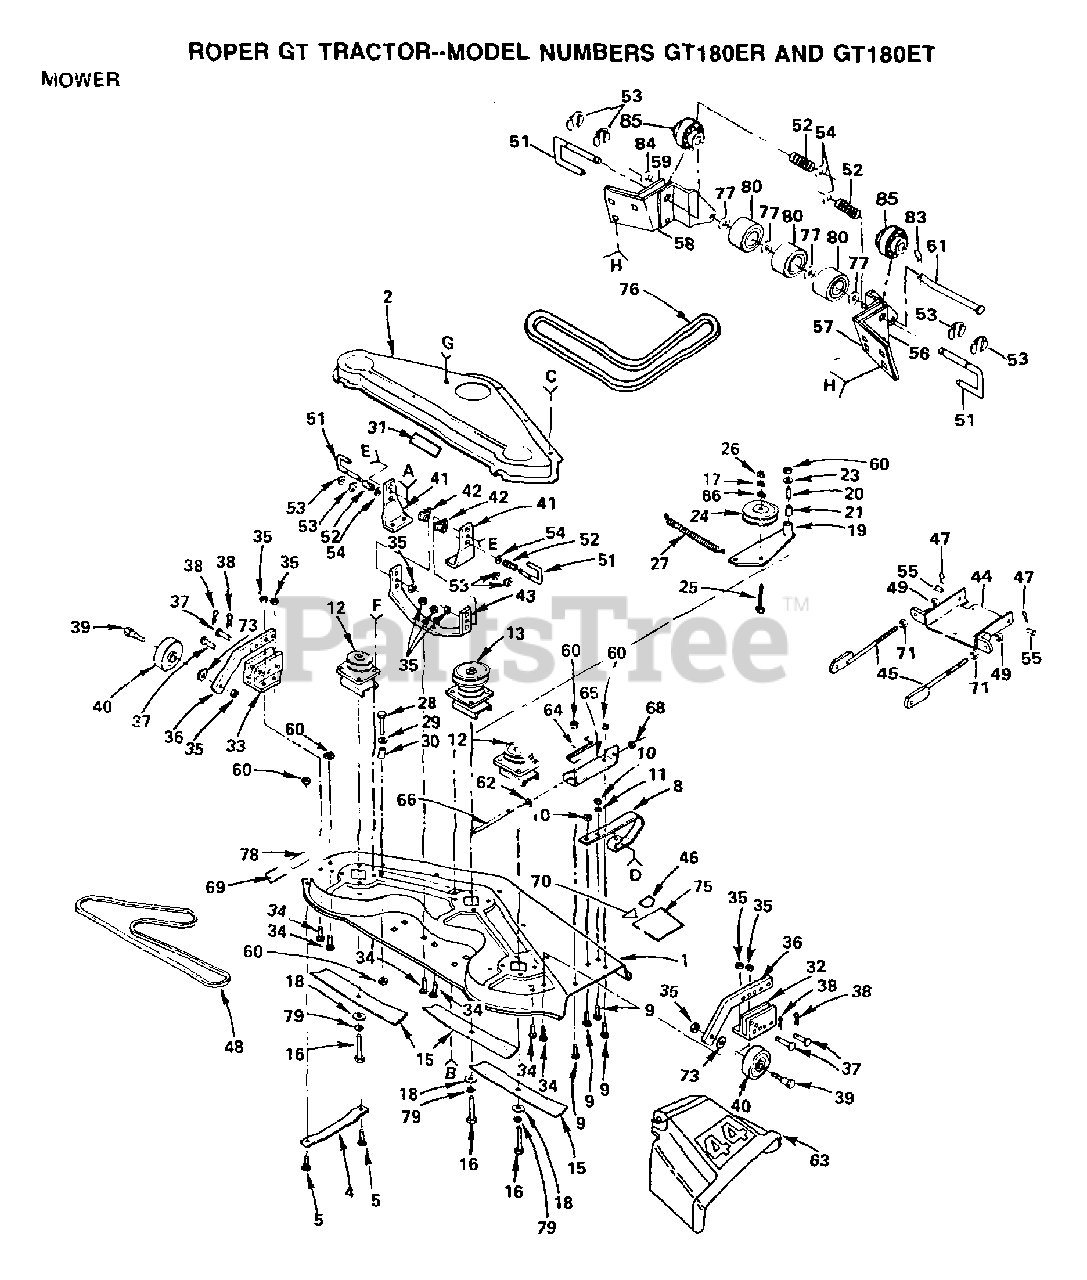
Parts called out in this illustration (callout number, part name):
2	DECK DRV COVE T
4	RUNNER-LH M
5	BOLT
9	BOLT
11	WASHER
16	BOLT.3/8-24X1-1/2
17	LOCKWASHER
18	WASHER
19	ARM ASSY GT
23	WASHER
24	IDLER-FLAT T
26	NUT.HEX.3/8-16UNC
27	SPRING T
28	BOLT
29	WASHER M
30	SPACER SPLIT LT
32	GUAGE WHL BRKT GT
33	GUAGE WHL BRKT GT
34	BOLT
36	GUAGE WHL BAR GT
39	BOLT M
40	WHEEL.GAGE.BLK.PL
41	SUSP BRKT GT
42	SPACER GT
43	SUSP BRACE GT
45	BRACKET.SUSPEN.AS
46	DECAL HYT
47	RETAINER.SPRING
48	V-BELT
49	NUT LTV
51	RELEASE PIN GT
52	SPRING M
53	KLIP RING
55	CLEVIS PIN GT
56	BRACKET T
57	BRACKET T
61	PIVOT PIN T
62	WASHER
63	DEFLECTOR SHIELD
66	ROD-HINGE T
69	DECAL INSTRUCTION CAUTION
70	DECAL - SAFETY STANDARD
71	NUT
73	WASHER
76	BELT-V.93.5.MWR
77	WASHER T
78	DECAL-INST YT
80	ROLLER T
83	SPRING.RETAINER
85	SPACER T
86	WASHER
